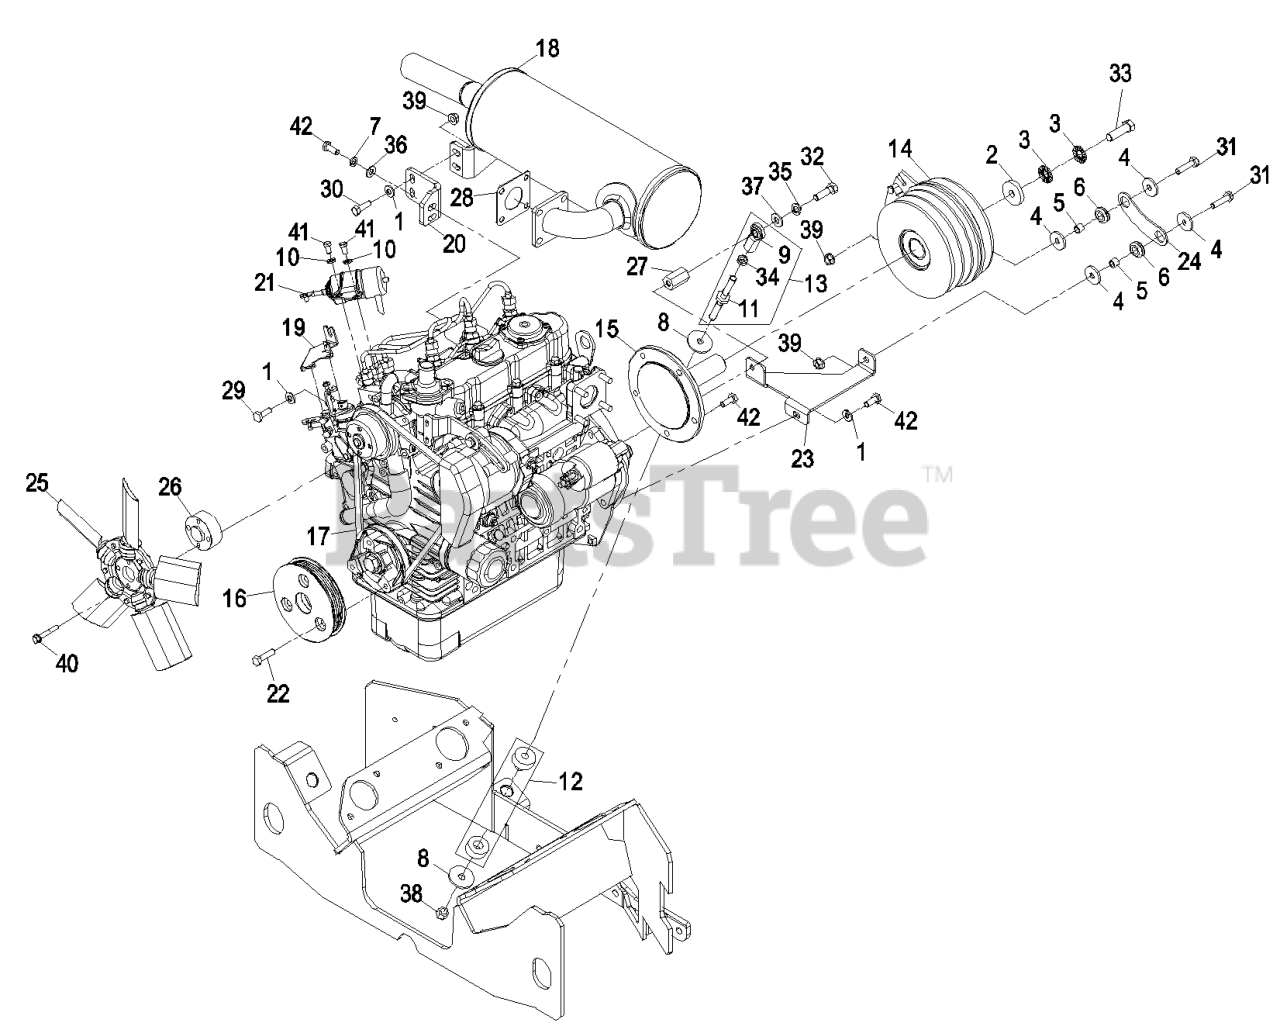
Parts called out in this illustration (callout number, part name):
1	WASHER-SPRING
2	WASHER-CLUTCH
3	WASHER-SPRING
6	GROMMET
7	WASHER-LOCK
9	JOINT-BALL, END
10	WASHER-LOCK
11	LINK,REAR A-T AXIAL
12	ISOLATOR-LINK
13	BALL JOINT LINK ASM
14	CLUTCH KIT
15	SHAFT, FLYWHEEL
16	SHEAVE, 5K 4.63
17	BELT,KUBOTA 902 ALT
18	ASM,KUBOTA MUFFLER
19	BRACKET-SUPPORT, THROTTLE
21	SOLENOID,FUEL
22	SCREW-HH
23	BRACKET, CLUTCH ANCHOR
24	LINK, CLUTCH
26	SPACER-FAN, 21MM
27	SPACER, A-T
29	SCREW-HH
30	SCREW-HH
31	SCREW-HH
32	SCREW-HH
33	SCREW-HH
34	NUT-HJ
35	WASHER-LOCK
36	WASHER-PLAIN
37	WASHER-FLAT
38	NUT-LOCK
40	SCREW-HHF
41	SCREW-HH
42	SCREW-HH
43	SPACER,1.63 X1.14 X .18
